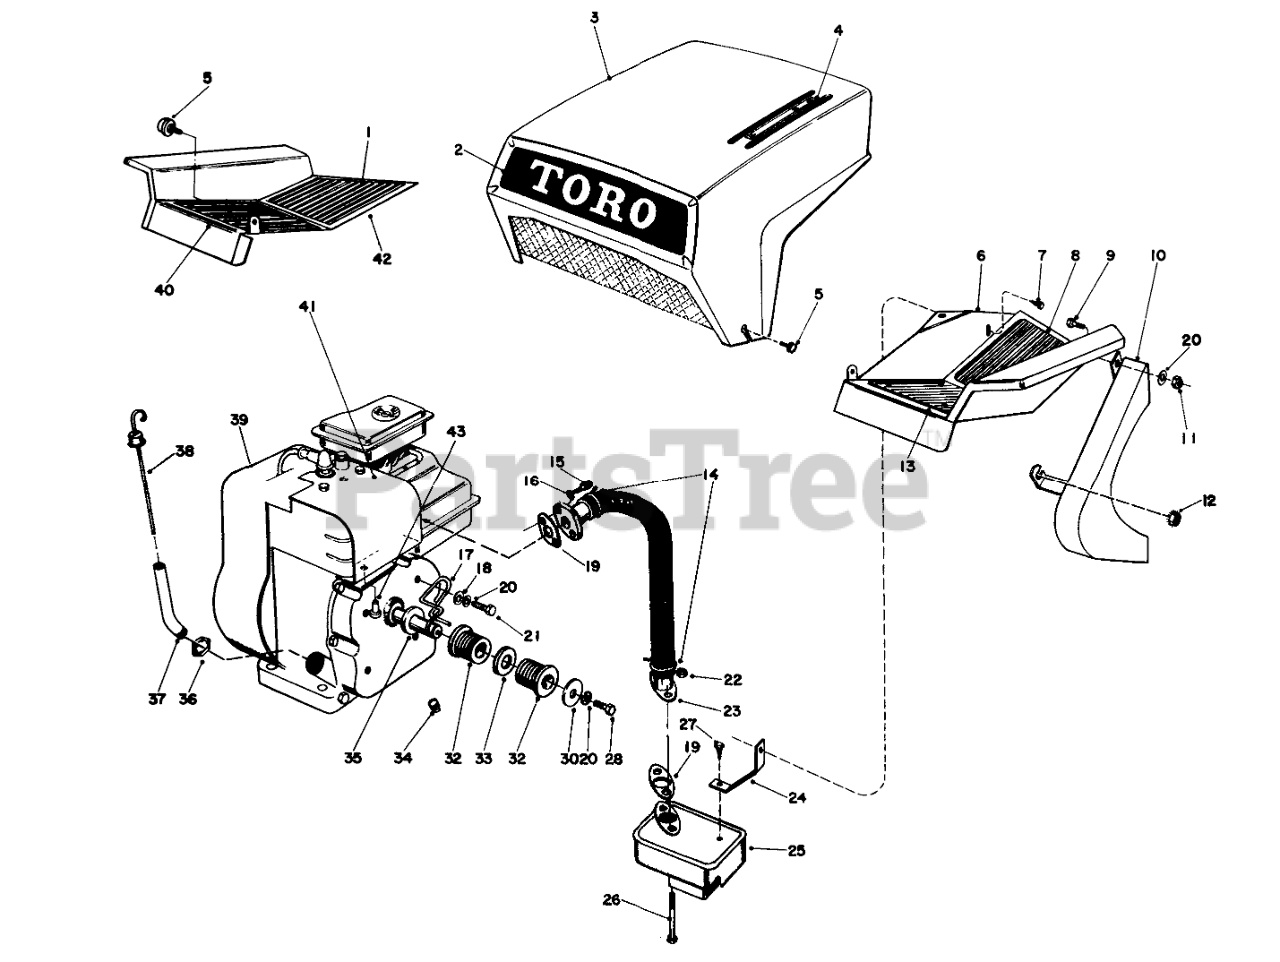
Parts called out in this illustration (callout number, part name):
1	Pad, Foot Rest
2	NAME PLATE DECAL
3	Shroud
4	Decal
5	THUMB SCREW WA
6	Fender & Insulation (Incl.Ref. #3 & 13)
7	10-16 X 3/8 THDG SCREW
8	Pad, Foot Rest
10	Chain Guard
11	NUT-HEX
12	NUT-KEPS
13	Pad, Foot Rest
14	Bale Tie
15	SCREW-HSH
16	WASHER-LOCK
17	Guide
18	WASHER-PLAIN
19	Gasket
20	WASHER-LOCK
21	SCREW-HH
22	NUT-KEPS
23	Exhaust Pipe Assembly (Incl. Ref. #14)
24	Muffler Support Bracket
25	Muffler
26	Capscrew
27	SCREW-HWHTF
28	SCREW-HH
30	Washer
32	Pulley, Engine Reel
33	WASHER-THRUST
34	PLUG-PIPE, SQH
35	Washer
36	PAL NUT
37	Extension Oil Fill
38	DIPSTICK ASM R
39	Engine
40	Pad Foot Rest
41	Deflector
42	Fender (Incl. Ref. #1 & 40)
43	BUMPER-RUBBER
